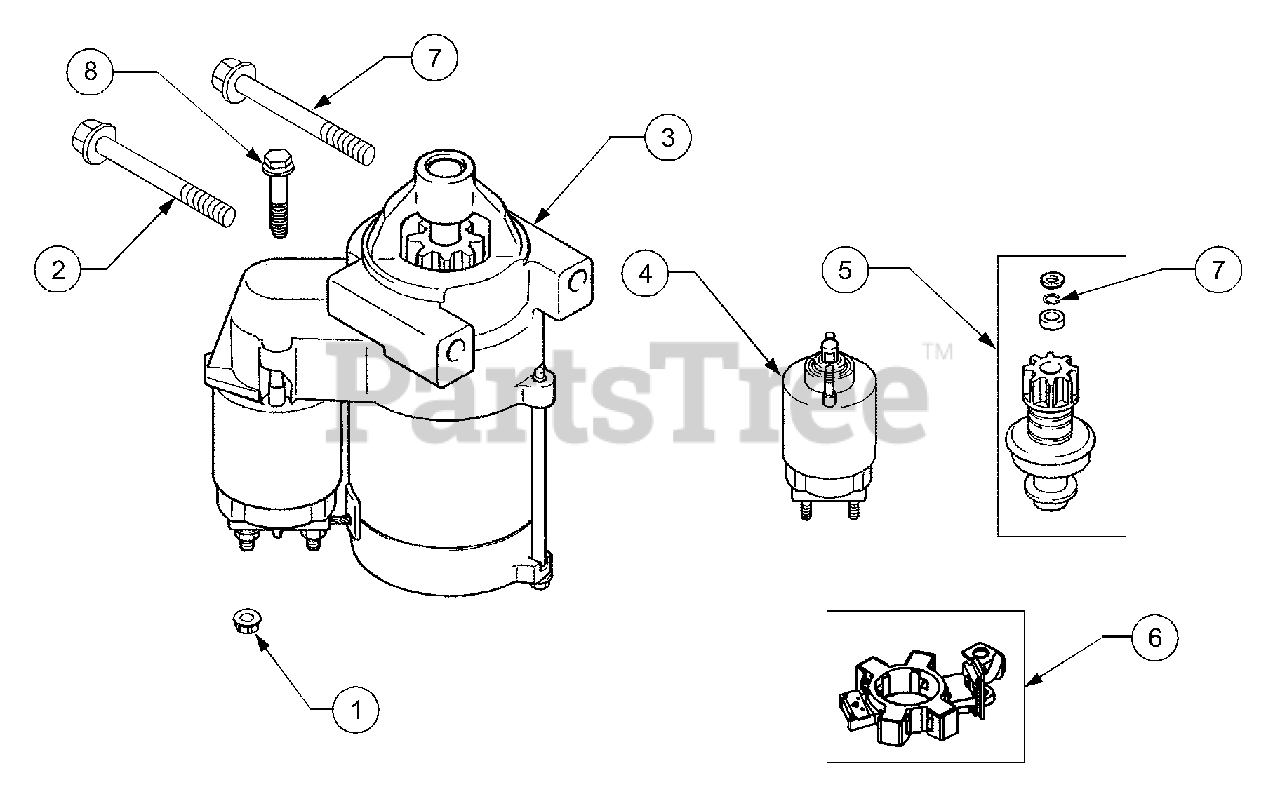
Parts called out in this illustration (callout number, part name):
1	Nut, Hex Flange M8 x 1.25"
2	Screw, Hex Flange M8 x 1.25 x 80
3	Starter, Solenoid Shift Assembly
4	Kit, Solenoid
5	Kit, Pinion Drive
7	Ring, Retainer
8	Screw, External Torx Hd.
